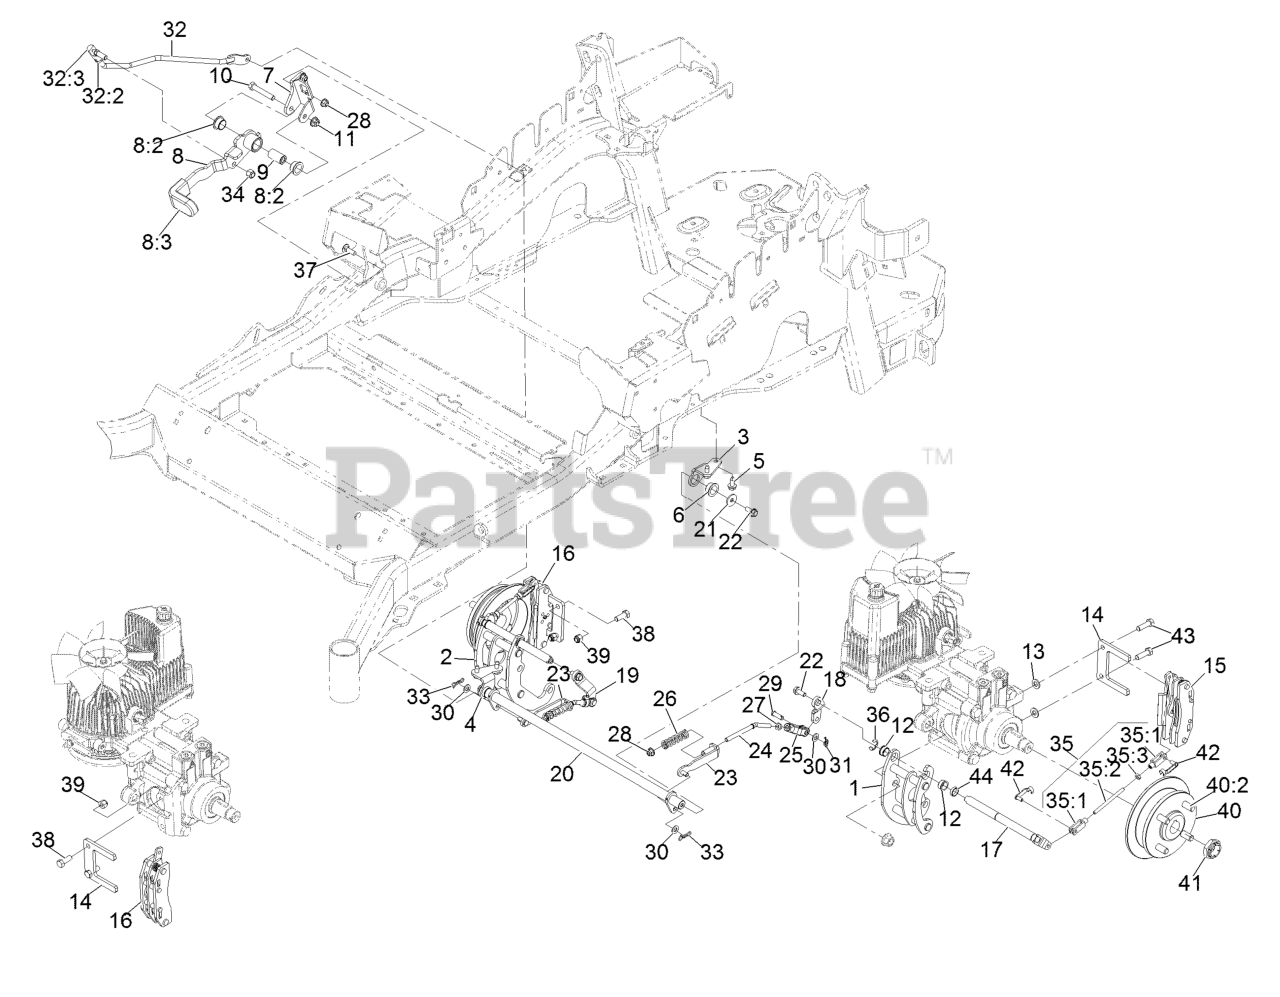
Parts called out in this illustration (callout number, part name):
1	Mount-Bellcrank, LH
2	Mount-Bellcrank, RH
3	Mount-Pivot, LH
4	Mount-Pivot, RH
5	Screw-HWH 5/16-18 X 3/4 Tf
6	Bushing-Flanged
7	Bracket-Mount
8	Brake Lever ASM W/ Grip
8:2	Bushing-Flanged
8:3	Grip-Lever
9	Handle-Pivot, Brake
10	Screw-HH 3/8-16 X 2 1/4
11	Nut-Nyloc 3/8-16 Flg
12	Bushing-Igus
13	Washer-3/8 SAE
14	Plate-Mount, Brake
15	Caliper-Brake
16	Caliper-Brake, RH
17	Bellcrank
18	Arm-Inner, LH
19	Arm-Inner, RH
20	Shaft-Cross
21	Washer-Flat
23	Bracket-L
24	Linkage-Mid
25	Yoke-Offset
26	Spring-Compression
27	Nut-Jam 5/16-24
28	Nut-Nyloc 5/16-18 Flg
29	Pin-Clevis 5/16 X 1 49/
30	Washer-5/16 SAE
31	Pin-Cotter, Locking
32	Front Linkage ASM
32:2	End-Tie Rod, RH
32:3	Nut-Jam 3/8-24
33	Pin-Cotter, Locking
34	Nut-Nyloc 3/8-24
35	Rear Linkage ASM
35:1	Yoke
35:2	Linkage, Rear
35:3	Nut-Jam 1/4-28
37	Bolt-Carriage 5/16-18 X
38	Screw-HH 3/8-16 X 1
39	Nut-Nyloc 3/8-16
40	Wheel Hub ASM
40:2	Stud-Wheel
41	Locknut
42	Pin-Clevis, Spring
43	Screw-HH 3/8-16 X 1 1/4 Patch Lock
